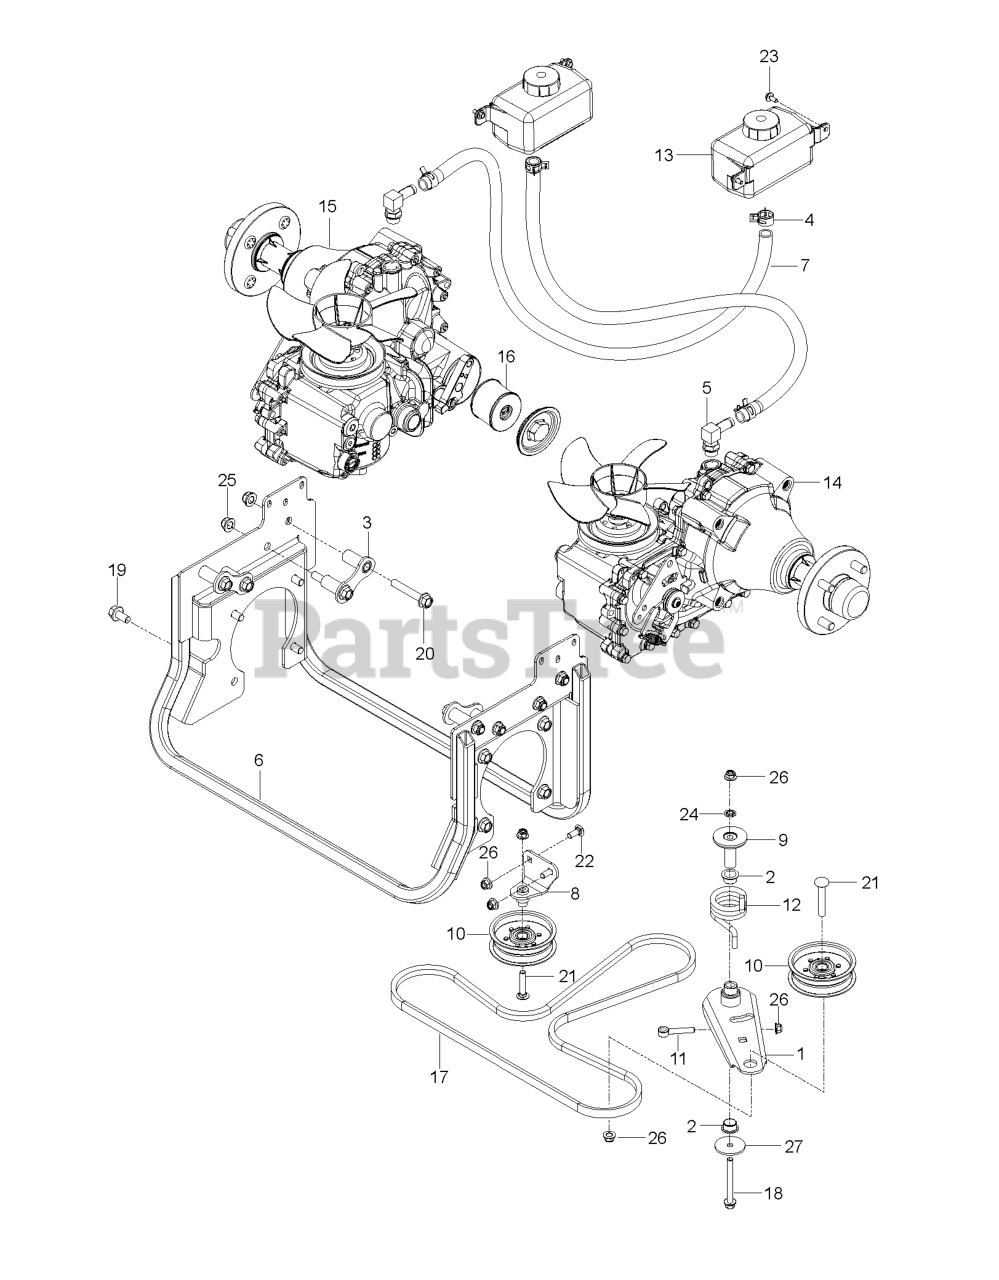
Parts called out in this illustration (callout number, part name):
1	ARM.PNT.IDLER.WELDMENT.EDIP
2	BEARING.FLANGED.PLASTIC.3/4ID
3	BRACKET.PNT.MTG.XMSN.EDIP
4	CLAMP.CT.15/16"HOSE.OD
5	FITTING, 4601-10-10 NOW
6	FRAME XMSN ZT-5400, BLACK X431
7	HOSE HYD, 5/8"ID. 7/8"OD, 350
8	MOUNT.PNT.IDLER.FIXED.EDIP
9	SHAFT.MOUNT.ARM.IDLER
10	PULLEY.IDLER.BACKSIDE
11	ROD.END.3/8-16 X 3.STEEL
12	SPRING.TORSION
13	HG_TANK, EXPANSION
14	TRANSMISSION.ZT-5400.LH
15	TRANSMISSION.ZT-5400.RH
16	HG_KIT, FILTER W/O-RING ZT5400
17	V-BELT.BX.69" ZT-5400
18	HHFS 3/8-16 X 3.5 GD 5 ZD
19	HHFS 1/2-13 X 1 GR5 ZD
20	HFFS 1/2-13 X 3 GD 5 ZD
21	RHSNB 3/8C X 2
22	RHSNB 3/8C X 1
23	SCREW.HX.WSH.HD
24	NUT 3/8 PALNUT RTNG BLK PHOS
25	NUT, 1/2-13 HEX FLG NYLOC ZD
26	NUT 3/8-16 HEX FLG NYLOC ZD
27	WASHER 12/32X2X10GA
